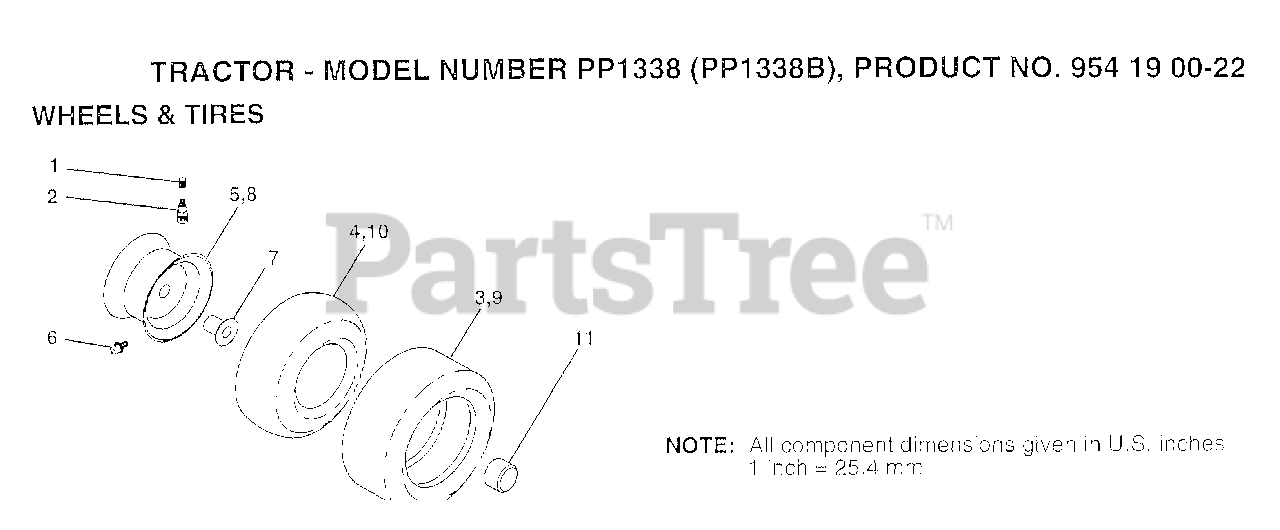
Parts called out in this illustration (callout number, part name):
1	VALVE CAP
2	VALVE STEM LT
4	TUBE.5.3/4.5/6
5	"RIM,FRT T"
6	FITTING LT
7	"FLANGE, BEARING"
8	"RIM 8"""
10	TUBE.18X9.5-8
11	HUB CAP
